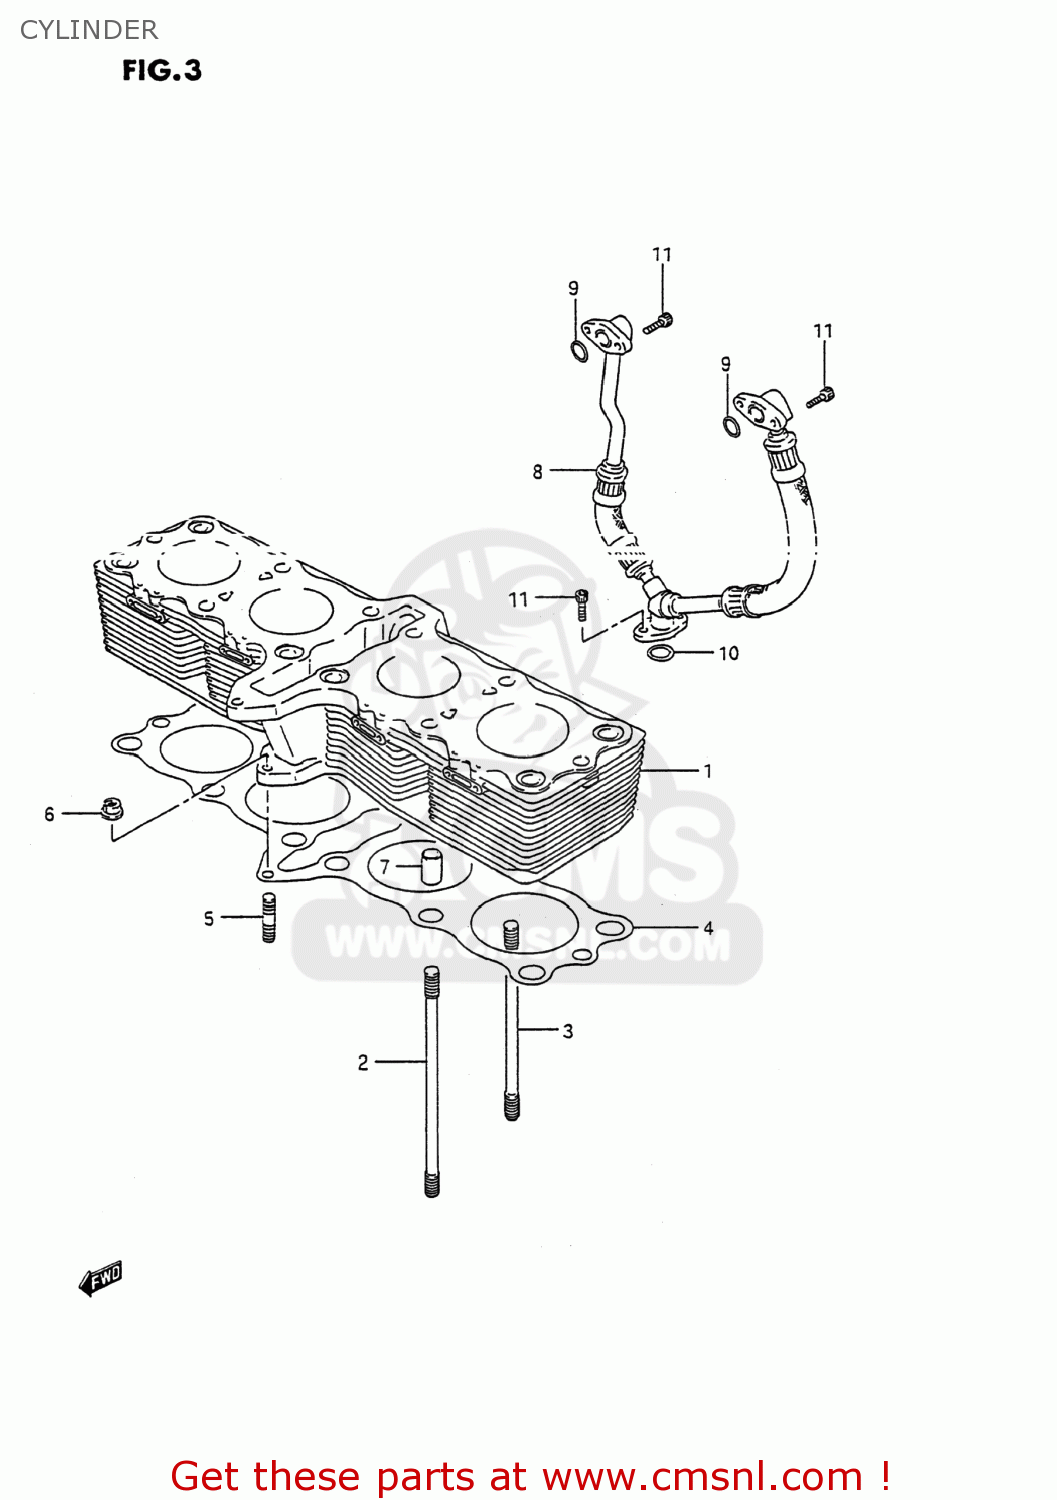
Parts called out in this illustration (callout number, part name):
1	CYLINDER
2	STUD BOLT (L:150)
3	BOLT,STUD
4	GASKET,CYLINDER (NAS)
5	STUD,M6X1X32
6	NUT
7	PIN
8	HOSE,OIL HEAD COOLER
9	O RING(D:2.5,ID:13.8)
10	O RING(D:2.4,ID:15.8)
11	BOLT
